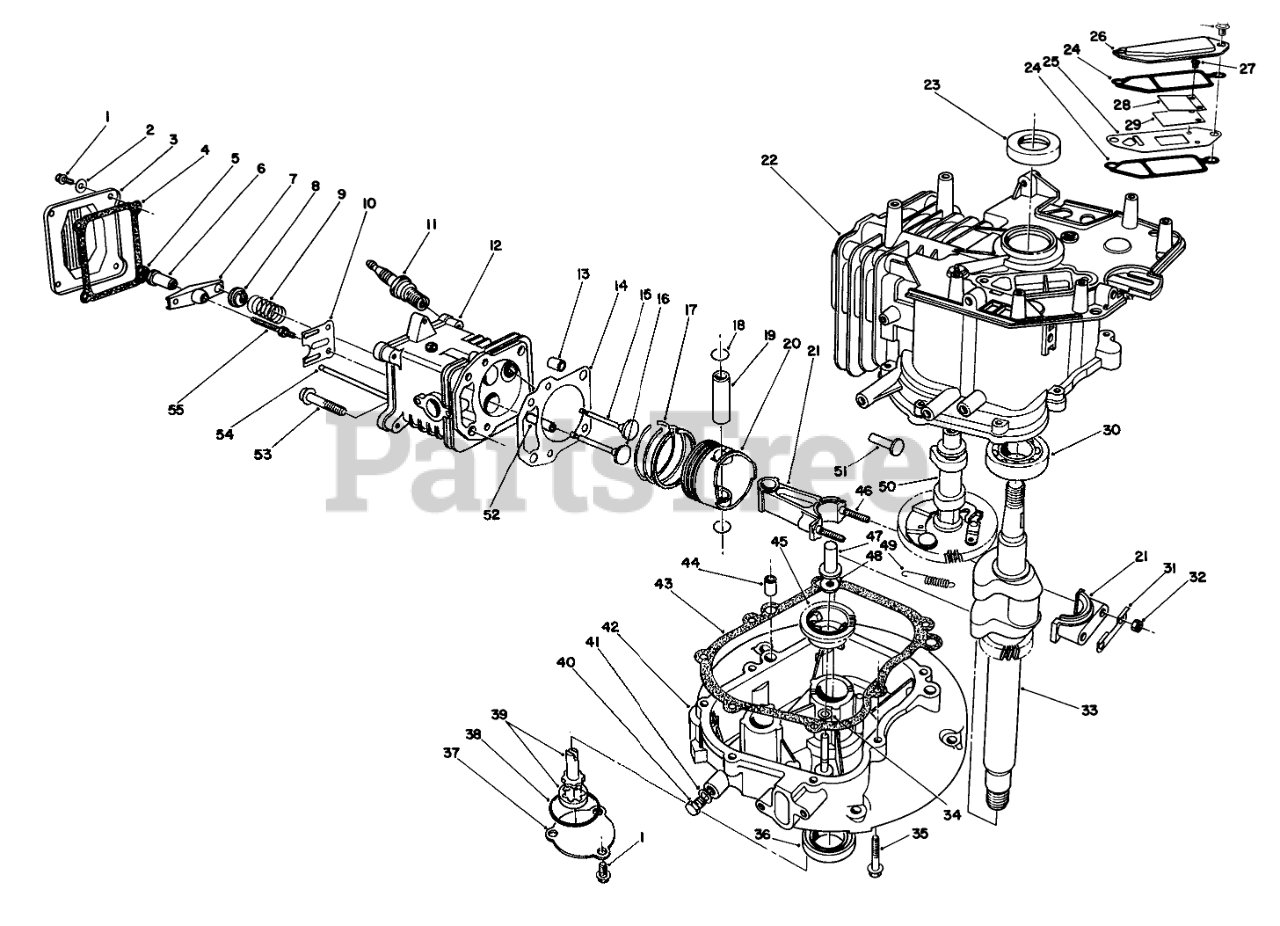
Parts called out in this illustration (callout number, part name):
2	WASHER
3	COVER
4	GASKET
6	PIVOT
8	RETAINER
9	SPRING
10	GUIDE
11	SPARK PLUG
12	Head-Cylinder (Incl. Ref. #52)
14	GASKET
15	VALVE-INTAKE
16	VALVE-EXHAUST
17	RING SET
18	CIRCLIP
20	PISTON
21	Connecting Rod Assembly (Incl. Ref. #31, 32 & 46)
22	Block-Engine (Incl. Ref. #23 & 30)
24	GASKET
25	Plate-Breather
26	COVER
27	Screw-Reed Valve
28	Retainer-Reed Valve
29	Valve-Reed
30	BEARING
31	Plate-Lock
33	CRANKSHAFT
34	WASHER
36	Oil Seal
37	COVER
38	O-RING
39	OIL PUMP
40	OIL DRAIN PLUG
41	GASKET
42	Crankcase
43	GASKET
45	GOVERNOR FLYWEIGHT ASM
47	PLUNGER
48	WASHER
49	SPRING
50	Camshaft Assembly (Incl. Ref. #49)
51	TAPPET
52	GUIDE
